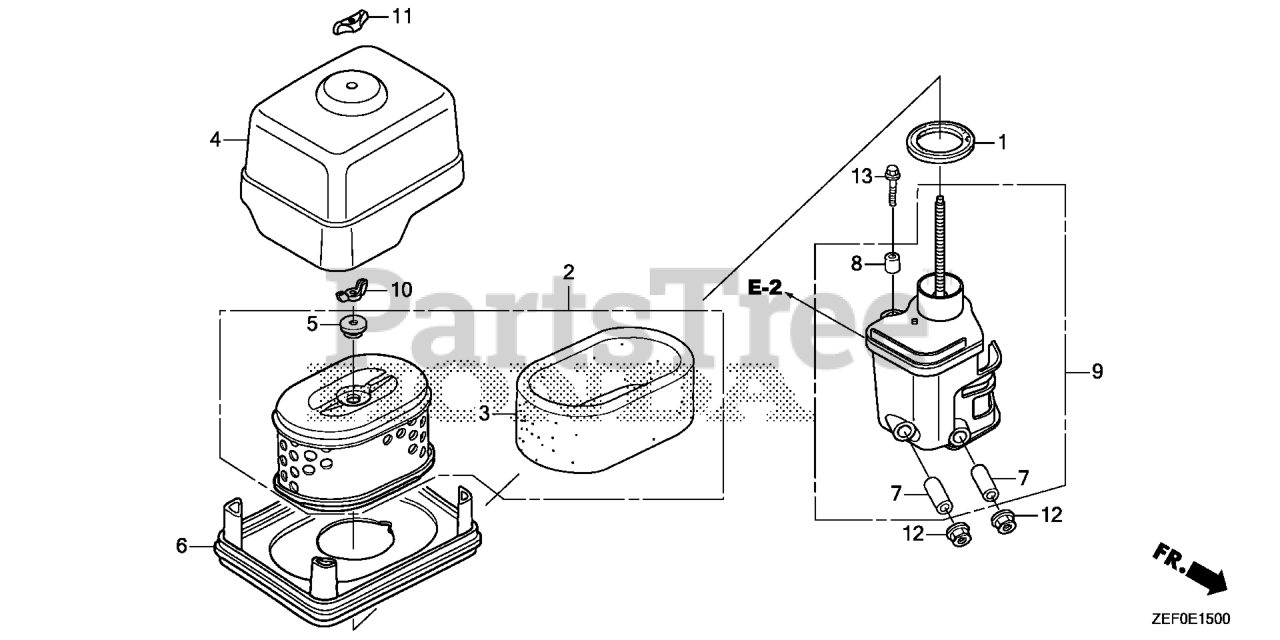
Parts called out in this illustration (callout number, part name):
1	GASKET, ELBOW
2	ELEMENT, AIR CLEANER (DUAL)
3	FILTER (OUTER)
4	COVER, AIR CLEANER
5	GROMMET, AIR CLEANER
6	NOSE, MUFFLER
7	COLLAR, AIR CLEANER Use from Engine SN 1786085.
8	COLLAR B, AIR CLEANER
9	ELBOW, AIR CLEANER
10	WINGNUT, TOOL BOX SETTING
11	NUT, AIR CLEANER
12	NUT, FLANGE (6MM)
13	BOLT, FLANGE (6X20)
